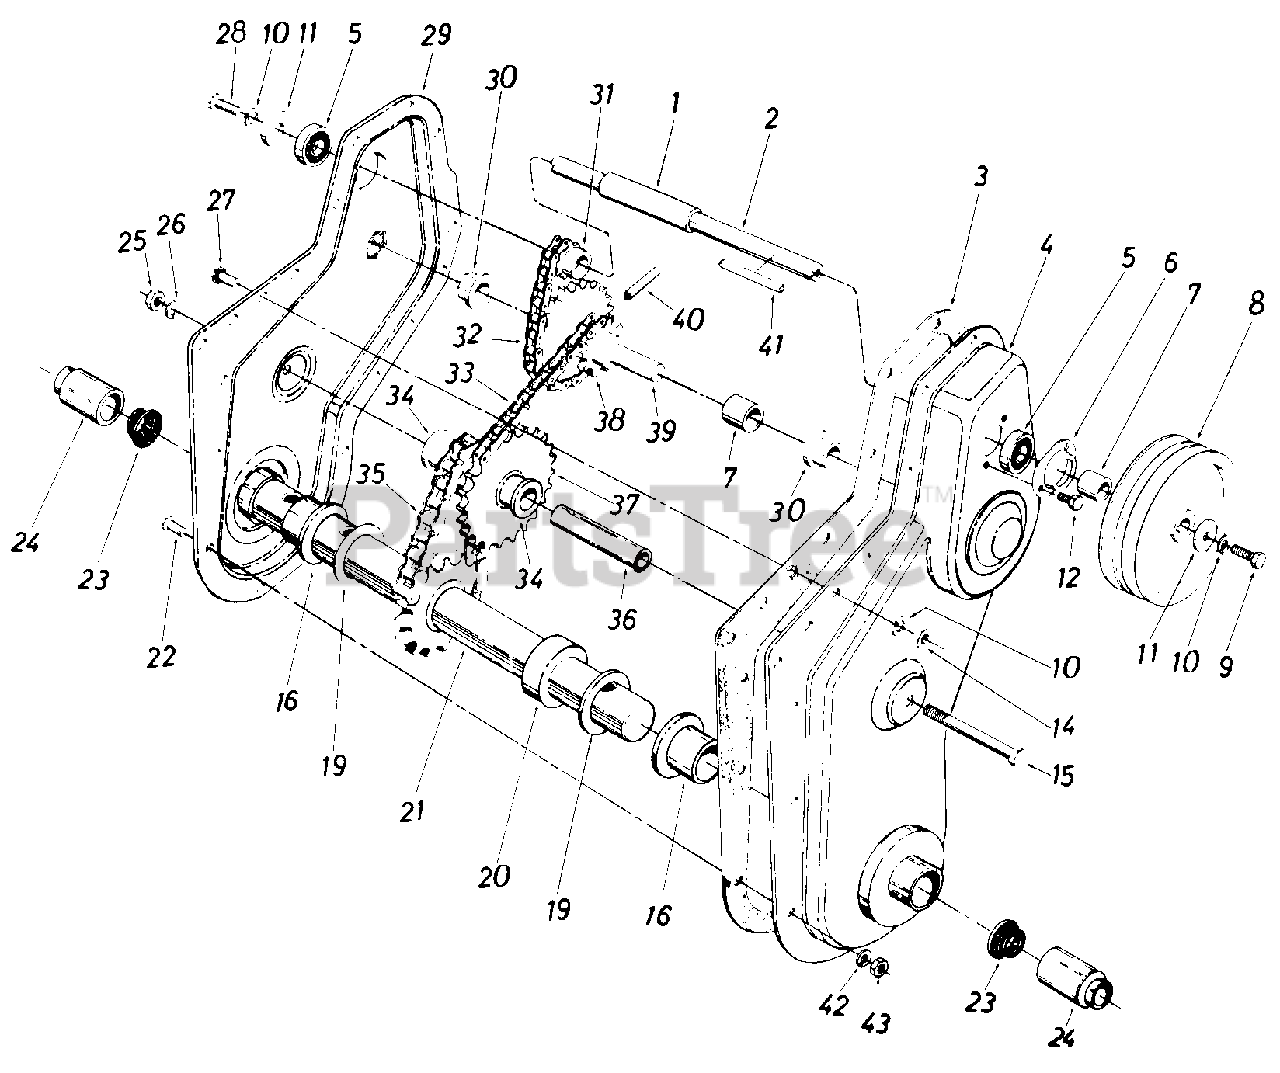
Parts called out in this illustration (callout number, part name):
1	Spacer .657 I.D. x .78 O.D. x 2.19" Lg.
2	Jackshaft
3	Housing Gasket
4	Housing Ass'y.-L.H. Half
5	Ball Bearing .625 I.D. x 1.375 O.D.
6	Bearing Housing
7	Spacer .635 I.D. x .88 O.D. x 1.03" Lg.
8	Chain Case Pulley 6.0" Dia.
9	Hex Bolt 5/16-18 x 1.0" Lg.
10	L-Wash. 5/16" I.D.
11	Fl-Wash. .344" I.D. x 1.125"O.D.
12	Hex Wash. Hd. Self-Tap Scr. 1/4-20 x .50" Lg.
14	Hex Nut 5/16-18 Thd.
15	Hex Bolt 3/8-16 x 3.25" Lg.
16	Flange Bearing
19	Flat Thrust Wash.
20	Step Spacer
21	Tine Shaft Ass'y.
22	Hex Bolt 1/4-28 x .62" Lg.
23	Seal Ring
24	Dust Cap
25	Hex Nut 3/8-16 Thd.*
26	L-Wash. 3/8" I.D.*
27	Hex Sems Bolt 5/16-18 x 1.00" Lg.*
28	Hex Bolt 5/16-18 x .62" Lg.
29	Housing Ass'y.-R.H. Half
30	Hex Flanged Bearing
31	Sprocket 10 Teeth 1/2" Pitch
32	#41 Chain 1/2" Pitch x 34 Links
33	#420 Chain 1/2" Pitch x 48 Links
34	Flange Bearing .625" I.D.
35	#50 Chain 5/8" Pitch x 28 Links
36	Sprocket Shaft
37	Sprocket Bearing Sleeve Ass'y.
38	Sprocket Sleeve Ass'y.
39	Sprocket Shaft
40	Spring Pin Spiral 1/4" Dia. x 1.5" Lg.
41	Square Key 3/16 x 3/16 x 1.50" Lg.*
42	L-Wash. 1/4" I.D.*
43	Hex Nut 1/4-28 Thd.*
